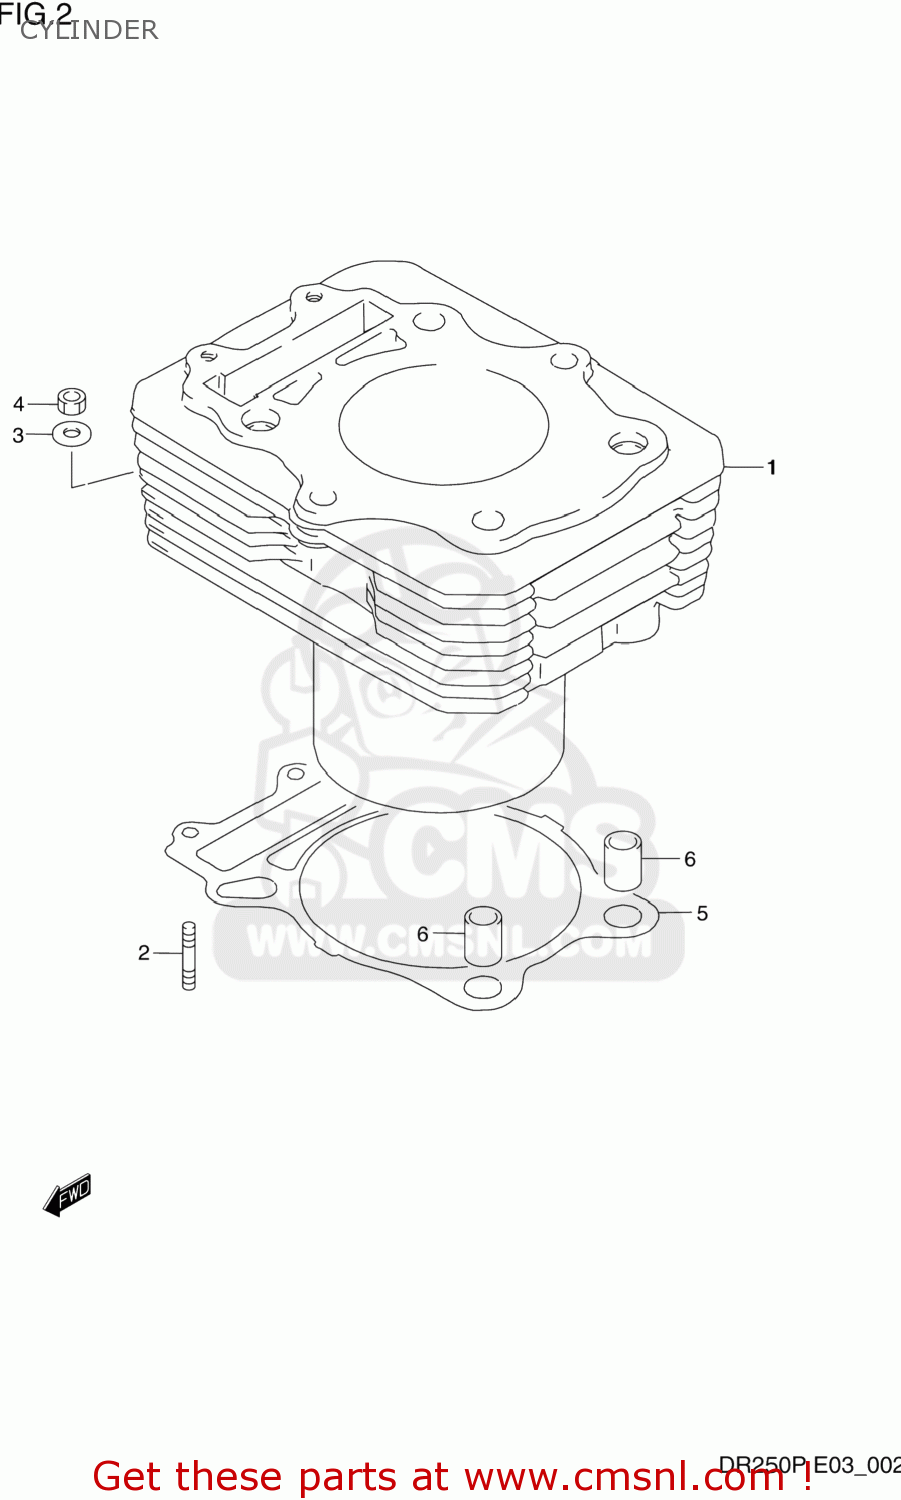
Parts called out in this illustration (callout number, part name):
1	CYLINDER
2	STUD 6X20
3	WASHER 6MM
4	NUT
5	GASKET,CYLINDER (NAS)
6	PIN
